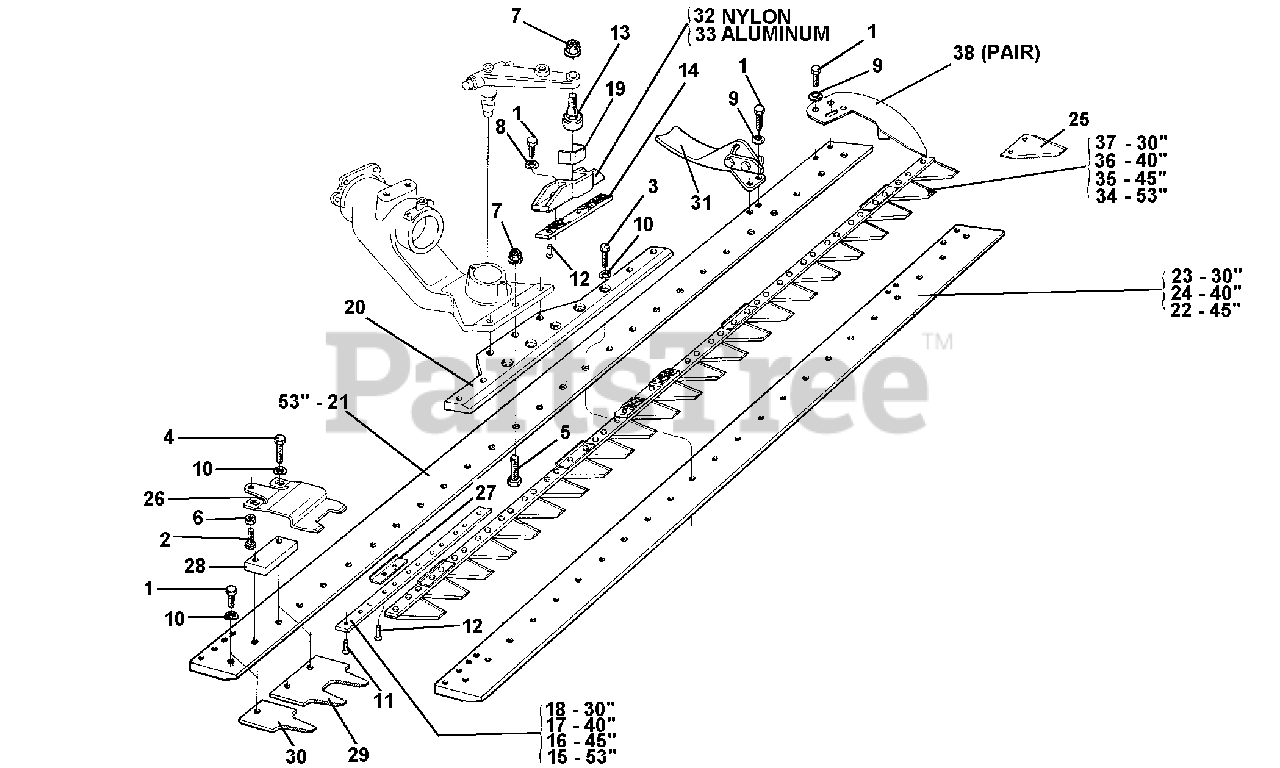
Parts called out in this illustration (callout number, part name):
1	SCREW M8 X 16
2	SCREW M8 X 20
3	SCREW M8 X 25
4	SCREW TE M8 X 30
8	WASHER, FLAT 8.4
9	SUPER WASHER 8 DIN 6796
10	WASHER, LOCK 8.4
11	RIVET 5.3 X 14
12	RIVET TSV 5.3 X 18
13	BLADE CONTROL PIN
14	PLATE FOR BLADE COUPLING
15	STRIP FOR BLADE MT. 1.35
16	STRIP FOR BLADE MT. 1.15
17	BLADE STRIP
18	BLADE STRIP
20	BAR COUPLING
21	SLIDE FOR CUTTER BAR
23	SLIDE COMBO BAR, 0.80
24	SLIDE COMBO BAR 1.0 MT
25	SECTION F. NARROW SCORED BLADE
26	BLADE HOLDER
27	PLATE FOR CLEANING
28	BLADE GUIDE BLOCK
29	DOUBLE FINGER
30	SINGLE FINGER
31	SKID, INTERMEDIATE
32	NYLON BLADE COUPLING
33	BLADE CONNECTION
34	SCORED CENTRAL KNIFE 1.35
35	SCORED CENTRAL BLADE 1.15 MT.
36	SCORED COMBO BLADE 1 M
37	SCORED BOMOB BLADE 0.80 M.
38	END GUARD-COMBO BAR (PR)
